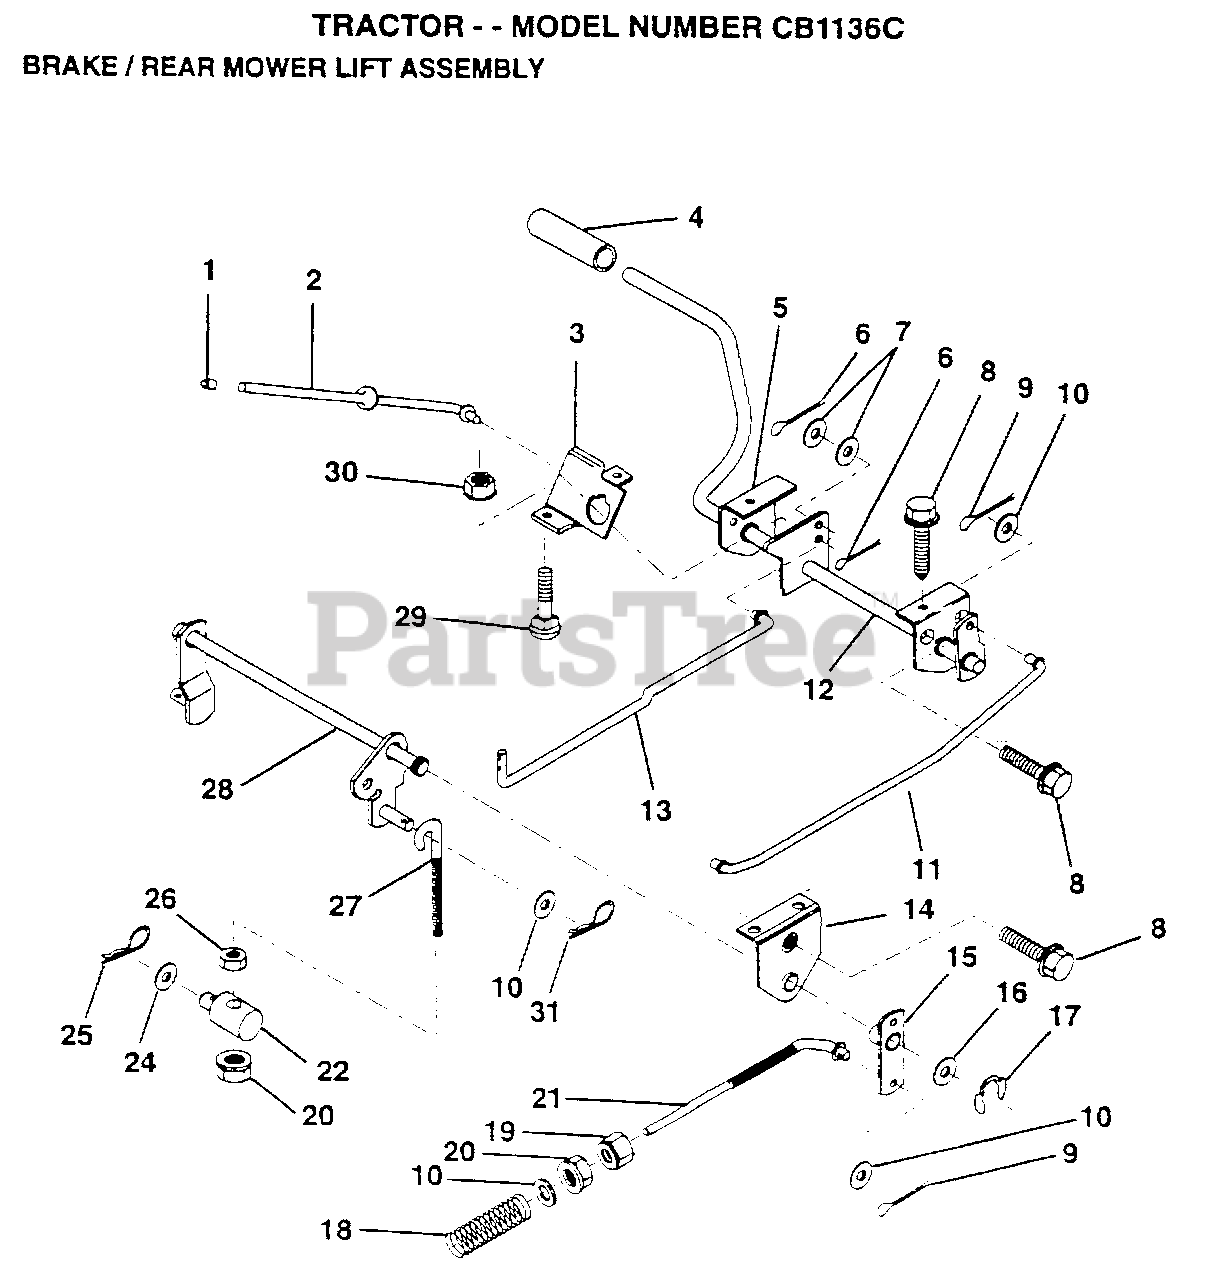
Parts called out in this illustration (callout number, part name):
1	PLUNGER CAP T
2	"ROD,PARK BRAKE"
3	"BRKT,PARK BRAKE"
4	FOOT PEDAL COVER
5	"BRKT,CLU PEDAL LH"
7	WASHER
8	SCREW LT
9	COTTER PIN
10	WASHER
11	"ROD,FRT BRAKE"
12	PEDAL ASM CL/BK36
13	"ROD,CLUTCH"
14	"BRKT,LIFT SHAFT"
15	PVT BRAKE ARM ASM
16	WASHER T
17	KLIP RING
18	SPRING ROD LT
19	NUT
22	TRUNNION.LIFT.
24	WASHER
25	SPRING.RETAINER
26	LOCKNUT
27	"LINK, MOWER REAR"
28	LIFT ASM MOW REAR
31	RETAINER.SPRING
